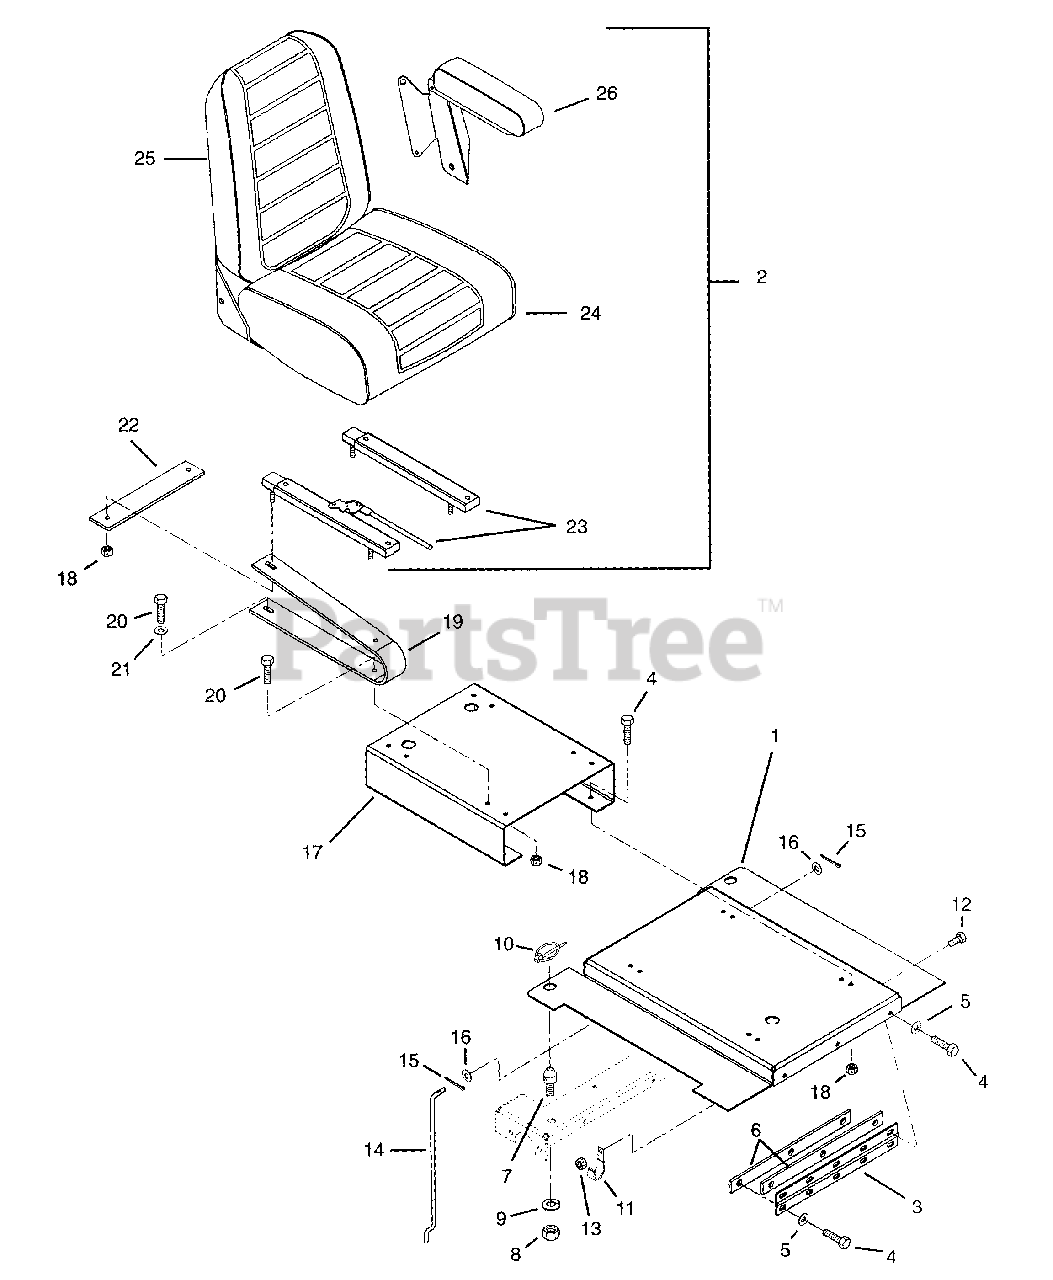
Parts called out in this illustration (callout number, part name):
1	Weldment, Seat Lid
2	Seat
4	Bolt-Hex .31-18 x .75 Grade 5
5	Washer-Flat-Steel .312 x .734 x .065
6	Plate, Clamping
7	Pin, Catch
8	Nut-Hex .50-13
9	Washer-Locking .50 x .125
10	Pin, Klik
12	Bolt-Hex .38-16 x .75 Grade 5
13	Nut-Locking-Center .38-16
14	Rod, Seat Lid Prop
15	Pin-Cotter .09 x .75
16	Washer-Flat-Steel .406 x .812 x .065
17	Riser, Seat
18	Nut-Locking-Center .31-18
19	Spring, Seat
20	Bolt-Hex .31-18 x 1.00 Grade 5
21	Washer-Flat-Steel .344 x .688 x .065
22	Bracket, Seat
23	Seat Slides with Handle
24	Seat Cushion with Switch
25	Cushion, Back
26	Armrest, Left Hand
26	Armrest, Right Hand
